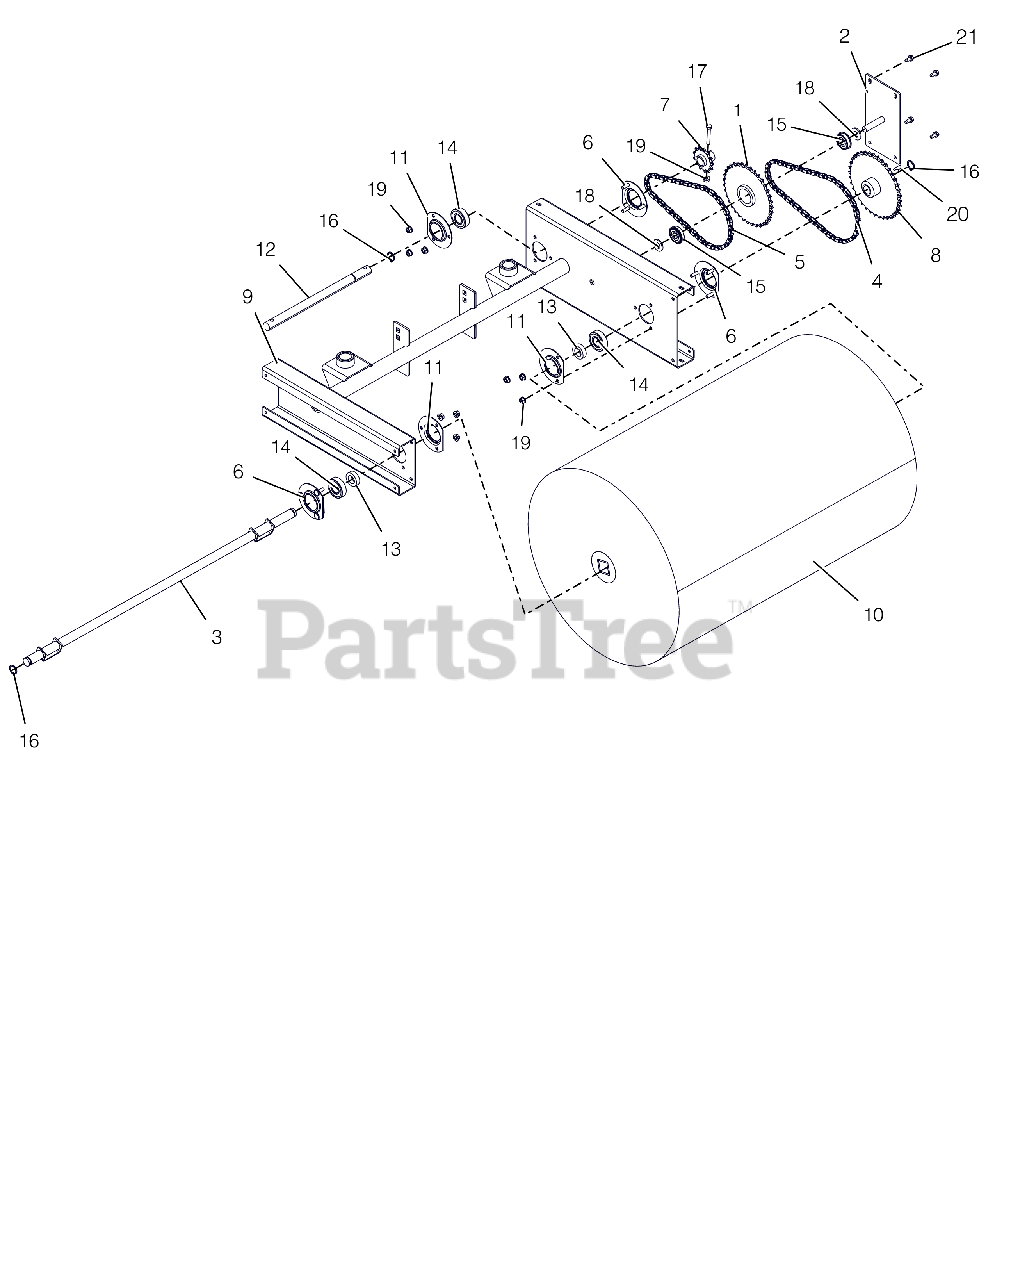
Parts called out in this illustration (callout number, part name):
1	SPROCKET, REDUCTION IDLER
2	PLATE, IDLER REDUCTION MOUNT
3	SHAFT, 28" BRUSH
4	CHAIN, #40-54 LINKS
5	CHAIN, #41-50 LINKS
6	BEARING FLANGE
7	SPROCKET, DRIVE
8	SPROCKET, DRIVEN
9	FRAME, POWER BROOM-DELUXE
10	BRUSH, 18"DIA X 28"WIDE
11	BEARING FLANGE
12	SHAFT, TRANSMISSION
13	SPACER .755X1.250X.370
14	BRG-BALL .750X1.750X.50
15	BRG-BALL .50X1.38X.438 SEALED
16	RG-RTNG-EXT .689X.078
17	@BLT-HEX .25-20X1.75 GR5 YWZC
18	WSHR-FL-STL .536X1.07X.109 YZ
19	@NUT-LK-TOP-FLG .25-20 YWZC
20	KEY-WDRF .188X.75X.313 SAE 9
21	SCR-TAP .25-20X.50 HWH TR YWZ
